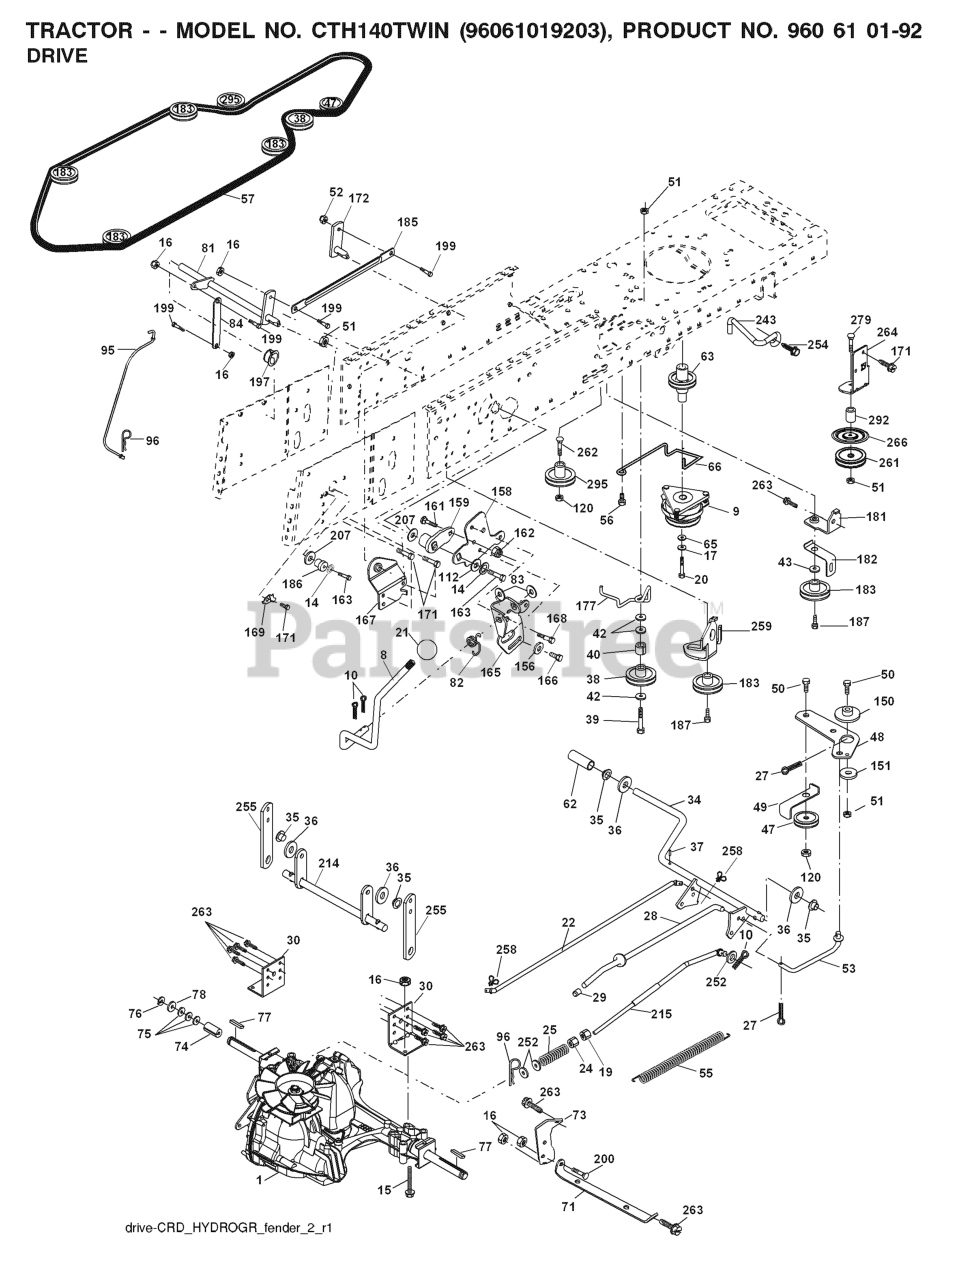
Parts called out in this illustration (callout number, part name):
8	ROD SHIFT FENDER ADJUST LT
9	CLUTCH.ELECTRIC.OGURA.EURO.
10	PIN COTTER
14	LOCKWASHER
15	BOLT HEX 5/16-18 GR 5
16	NUT.71038.31-18.HEX.NYLOCK
17	LOCKWASHER
19	NUT
20	BOLT HEX 7/16-20X4-1/4"
21	KNOB.DUCKHEAD.1/2
22	ROD
24	NUT
25	SPRING BRAKE ROD
27	COTTER PIN
28	ROD, PARKING BRAKE
29	PLUNGER CAP
30	BRKT, TRNSXLE MNT 20"
34	SHAFT, FOOT PEDAL
35	BEARING.NYLON
37	DRIVE PIN
38	PULLEY.FLAT
42	WASHER
47	IDLER PULLEY
48	BELLCRANK, CLUTCH
49	RETAIN BELT
50	BOLT.3/8-16X1.50
52	LOCKNUT
53	LINK.CLUTCH.7.66.2005
55	SPRING, RETURN LT
56	SCREW.3/8-16
57	V-BELT 113"
62	PEDAL COVER T
63	PULLEY.ENGINE.CVX.LT
66	KEEPER BELT ENGINE
71	STRAP TORQUE LH HYDRO
73	STRAP TORQUE RH HYDRO
74	SPACER AXLE
77	SQUARE KEY
81	ASM.CROSS.SHAFT.REAR.CRD.0510
82	SHIFT SPRING
83	WASHER
84	LINK.PNT.TRANSAXLE.0510.CRD
95	LINK
96	RETAINER M
120	NUT LOCK FLG 3/8-16 UNC
150	BUSHING.BELLCRANK.GRD.DR
151	WASHER 12/32X2X10GA
156	WASHER.SRRTD.5/16
158	BRACKET
159	RB HUB.SHIFT
161	BOLT
162	NUT.CROWNLOCK.1/4
165	RP BRACKET
166	CAPSCREW.HXHD.FLG.5/16-18X.625
167	BRACKET.SUPT.SHIFT.CRD
168	BOLT.SHOULDER.5/16-18X
169	PLATE.FASTENING.CROSS.SHAFT
172	LINK
181	BRACKET
182	BELT GUIDE
183	PULLEY.V-IDLER.GRND.DR
185	LINK
186	HUB.TAPERED.ROUND.CRD
187	BOLT.5/16-18X1.25
197	NYLINER SNAP 5/8" ID
199	BOLT SHOULDER 5/16-18 UNC
207	WASHER NYL
214	LEVER
215	ROD
243	BRACKET, ANTI-ROTATION
252	WASHER
254	SCREW 3/8-16X1
255	SHAFT
258	CLIP RETAINER
259	BRACKET
261	FLAT IDLER PULLEY
263	SCREW, 3/8-16X3/4
266	PROTECTOR
292	SPACER
295	PULLEY IDLER COMPOSITE
